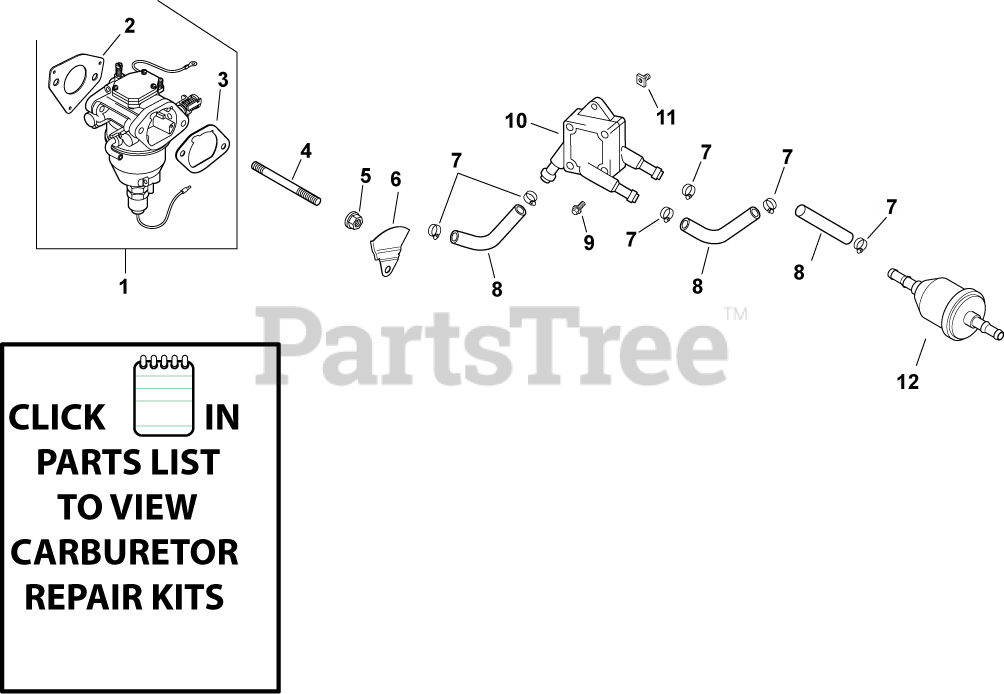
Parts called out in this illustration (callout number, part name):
1	KIT, CARBURETOR W/GASKET - DISCONTINUED
2	GASKET, CARBURETOR
3	GASKET, AIR CLEANER BASE
4	STUD,M6X1.0X96
5	NUT, FLG M6X1.0
6	BAFFLE, SPIT-BACK CUP-USE 24 063 105-S
7	CLAMP, HOSE (KM)-USE 25 237 31-S
8	HOSE,LW PERM.FUEL 24.00"-USE 25 111 81-S
9	SCREW, TAP M6X1.7X18
10	PUMP, FUEL
11	NUT, PLASTIC (KM)-USE 25 100 37-S
12	FILTER,FUEL 51 MICRON (FUEL PUMP)
